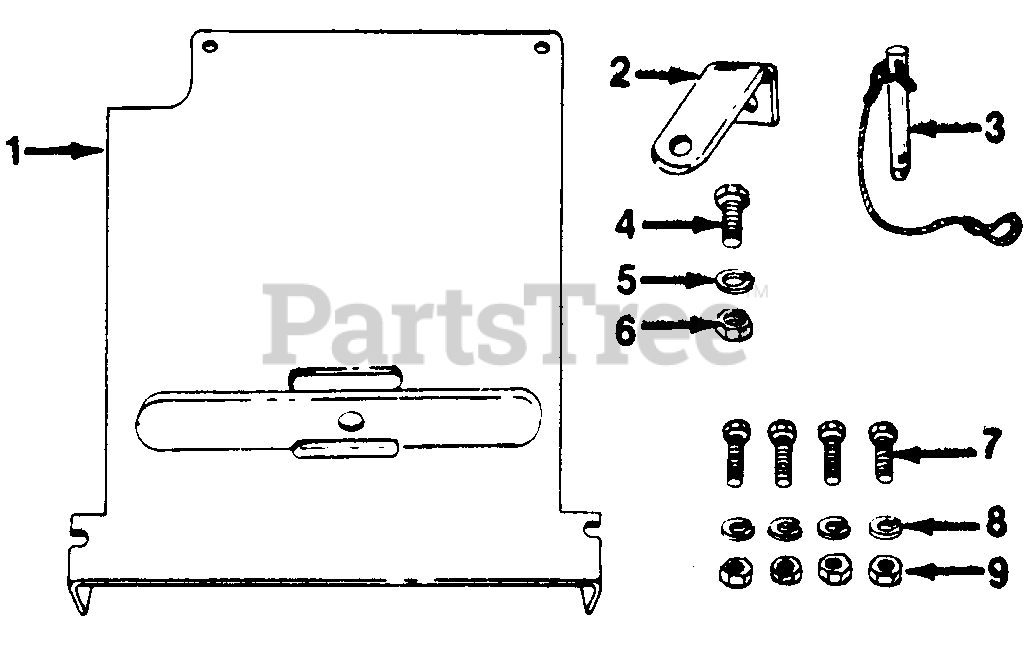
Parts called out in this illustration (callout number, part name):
1	Hitch Plate
2	HitGh Bracket
3	Hitch Pin
4	Hex Scr. 3/8-16 x 1" Lg.
5	L-Wash. 3/8" Scr.
6	Hex Nut 3/8-16 Thd.'
7	Hex Scr. 5/16-18 x .75" Lg.
8	L Wash. 5/16" Scr.
9	Hex Nut 5/16-18 Thd.'
